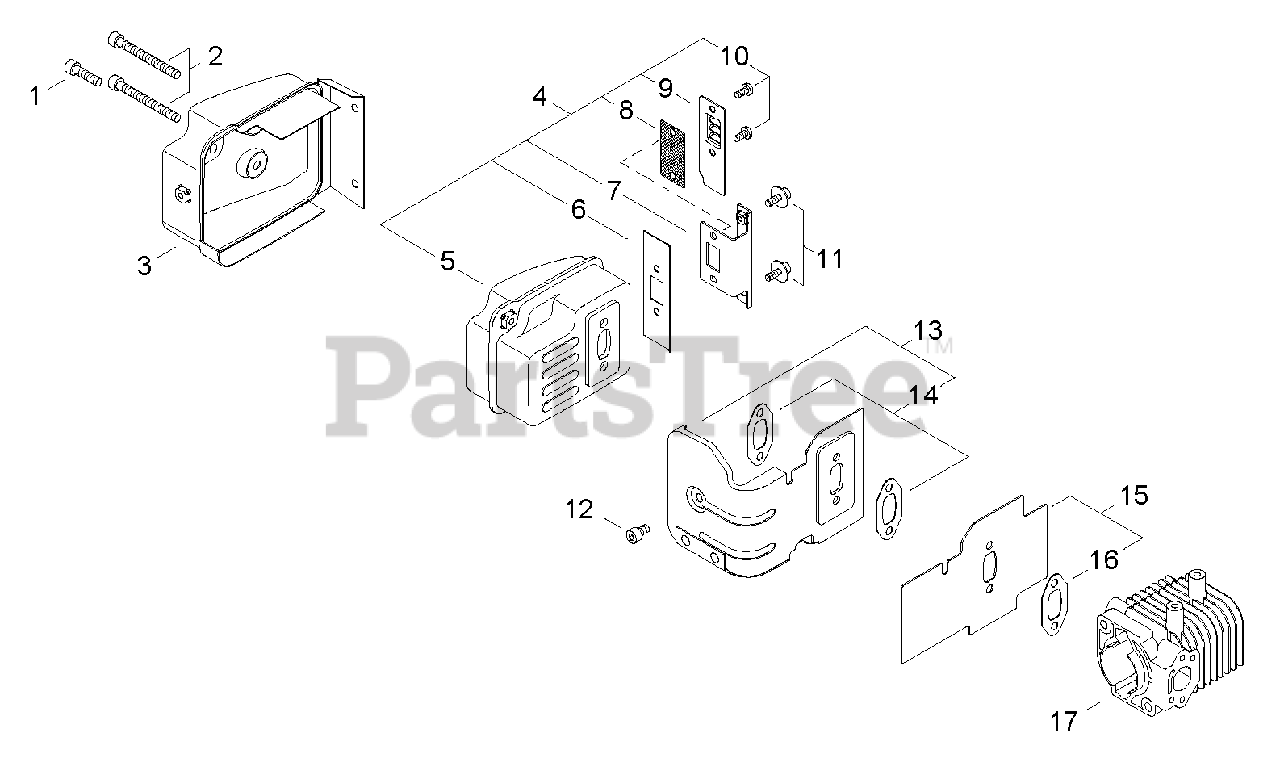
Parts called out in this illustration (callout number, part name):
1	SCREW - 5X20
2	SCREW - 5
3	COVER, MUFFLER
4	MUFFLER ASSY
5	MUFFLER
7	BRACKET, MUFFLER
8	SCREEN, SPARK ARRESTOR
9	GUIDE, EXHAUST
10	SCREW - 4X8
11	SCREW - 4X8
12	SCREW - 5X8
13	HEAT SHIELD KIT
14	HEAT SHIELD KIT
15	EXHAUST SHIELD KIT
16	HEAT SHIELD KIT
17	CYLINDER
